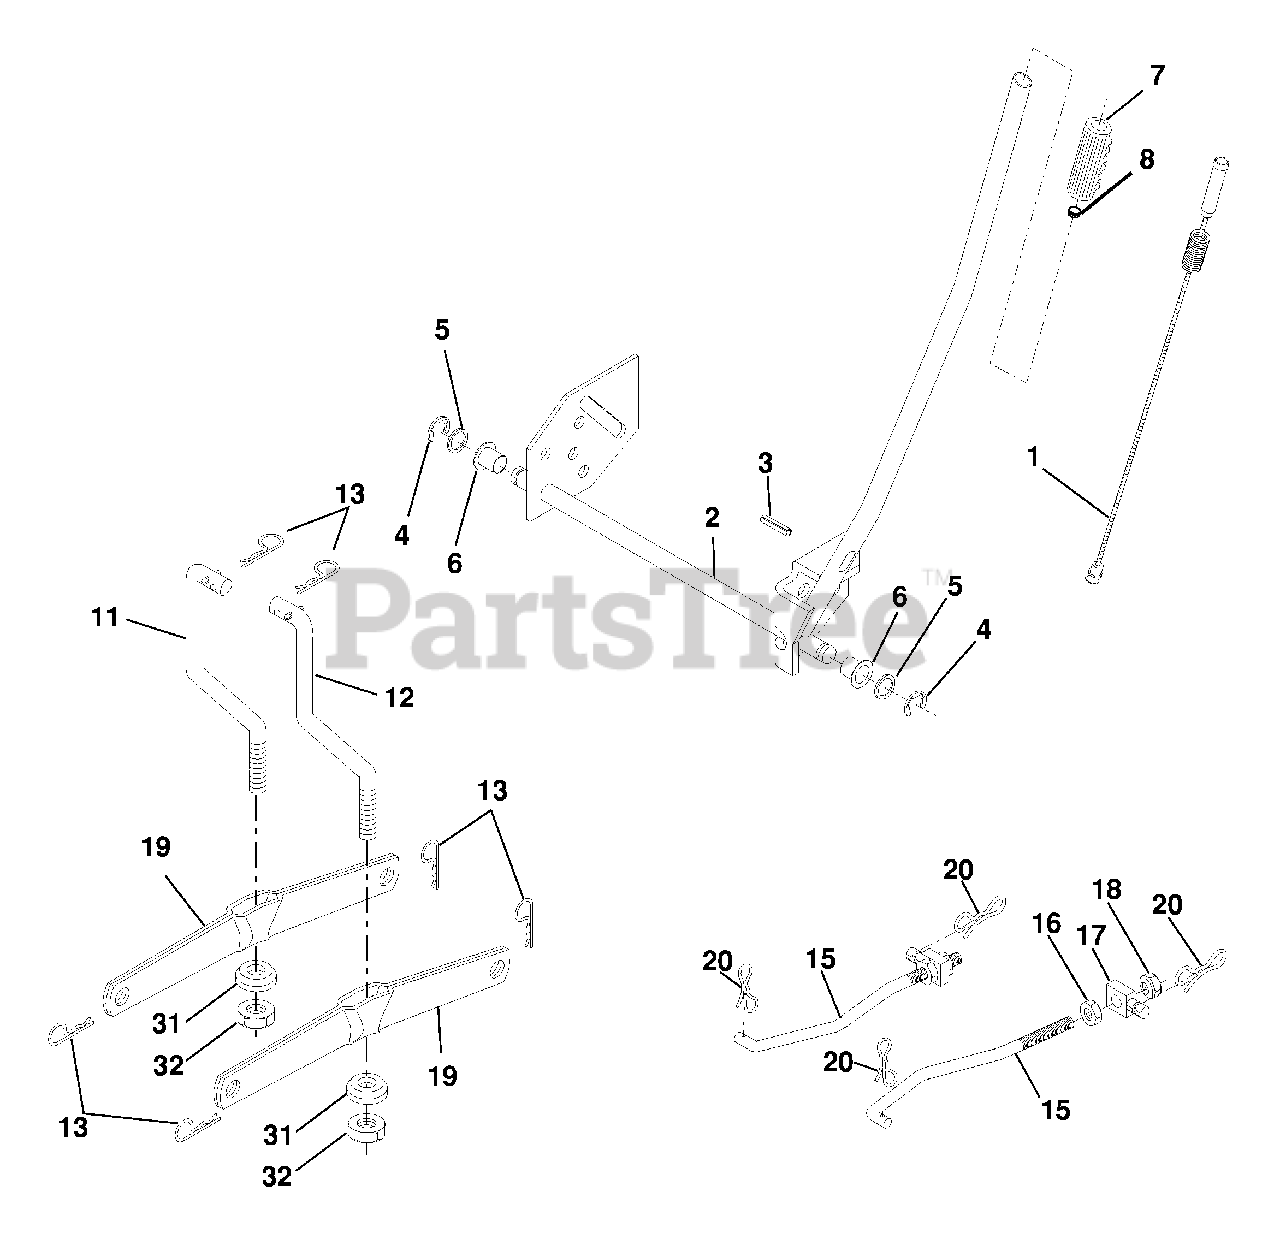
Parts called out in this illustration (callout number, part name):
1	Wire Asm Inner/Sprg W/plunger
2	Shaft Asm Lift RH w/Inf
3	Pin Groove 2"
4	E Ring #5133-62
5	Washer 21/32 x 1 x 21 Ga.
6	Bearing Nylon Blk 629 Id
7	Grip Handle
8	Button Plunger
11	Link Lift LH Fixed Length
12	Link Lift RH Fixed Length
13	Retainer Spring
15	Link Front
16	Nut Jam Hex 1/2-13 unc
17	Trunnion
18	Nut Lock W/Wsh 1/2-13 unc
19	Arm Suspension Rear
20	Pin Cotter 7/16 Bow Tie Lock
31	Bearing Pvt Lift
32	Nut Crownlock 3/8 - 24
